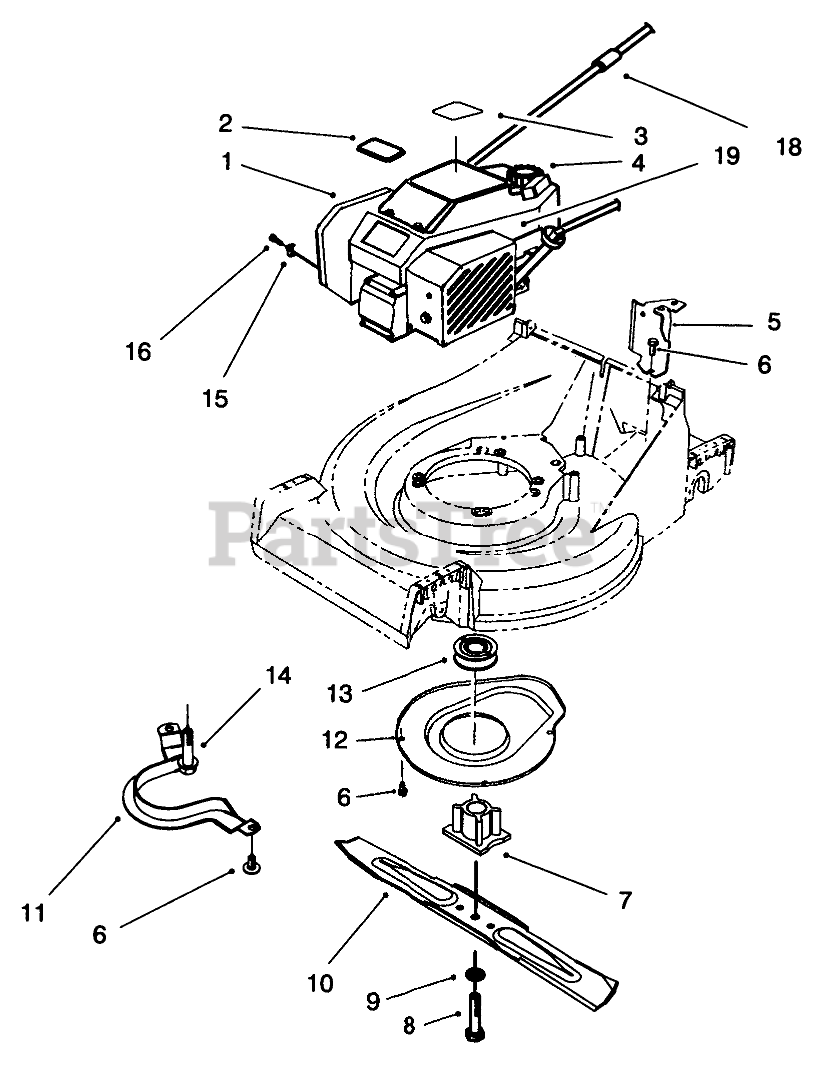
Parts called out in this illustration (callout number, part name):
1	Engine
2	PLATE-LOGO
3	DECAL - ENGINE
4	CAP-GAS
5	Bracket-Cable Support
6	SCREW-HWHTF
7	BLADE RETAINER
8	SCREW-BLADE
9	WASHER-LOCK
10	Key
11	Guide-Belt
12	Cover
13	PULLEY-DRIVE, ZONE START
14	SCREW-HWH
15	CLAMP-CASING
16	CLAMP SCREW F/W ENGINE
18	STOP-ROPE
19	COVER - BRAKE F/W
